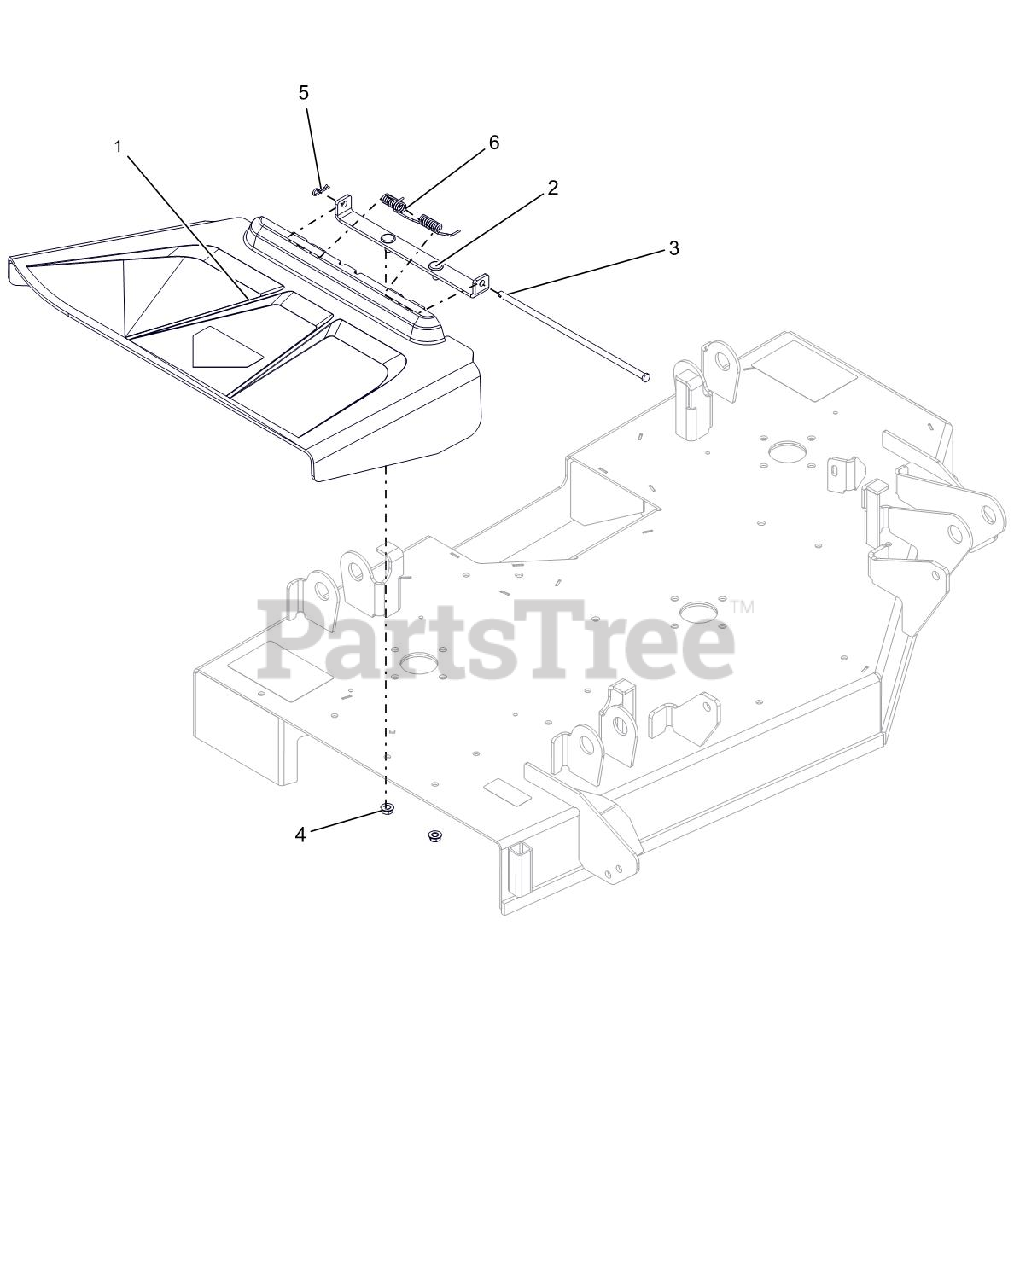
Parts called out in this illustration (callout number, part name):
1	CHUTE, SIDE DISCHARGE
2	WLDMT, CHUTE MT BRKT
3	PIN, 5/16 X 10.5
4	@NUT-LK-TOP-FLG .31-18 YWZC
5	PIN-HAIR INT .08X.18X1.18 YWZC
6	SPRING-TORSION
